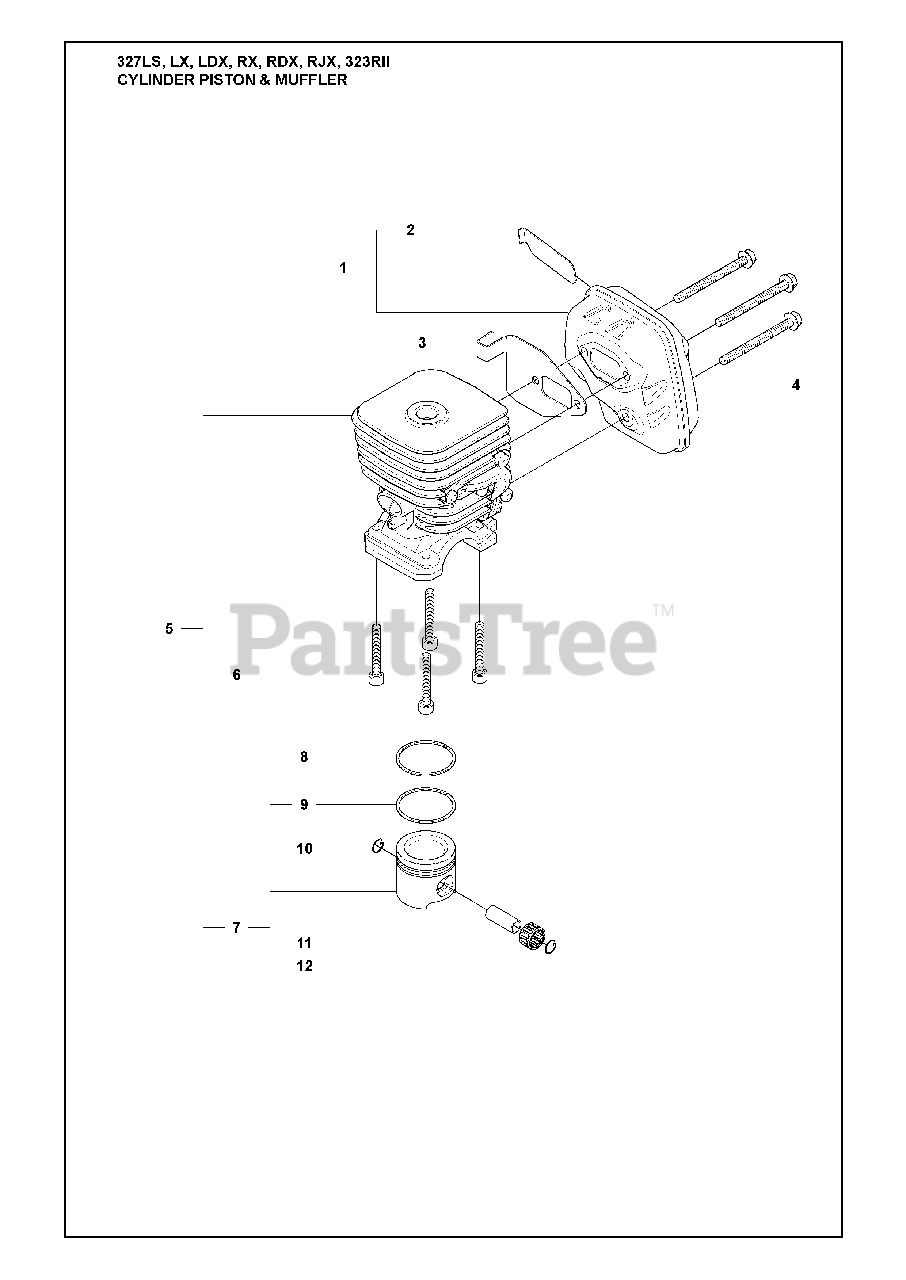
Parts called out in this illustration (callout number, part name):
1	MUFFLER KIT
2	SPARK ARRESTOR SCREEN
4	SCREW EHHFM
5	CYLINDER COMPL
6	%SCREW
8	PISTON RING
9	PISTON RING
